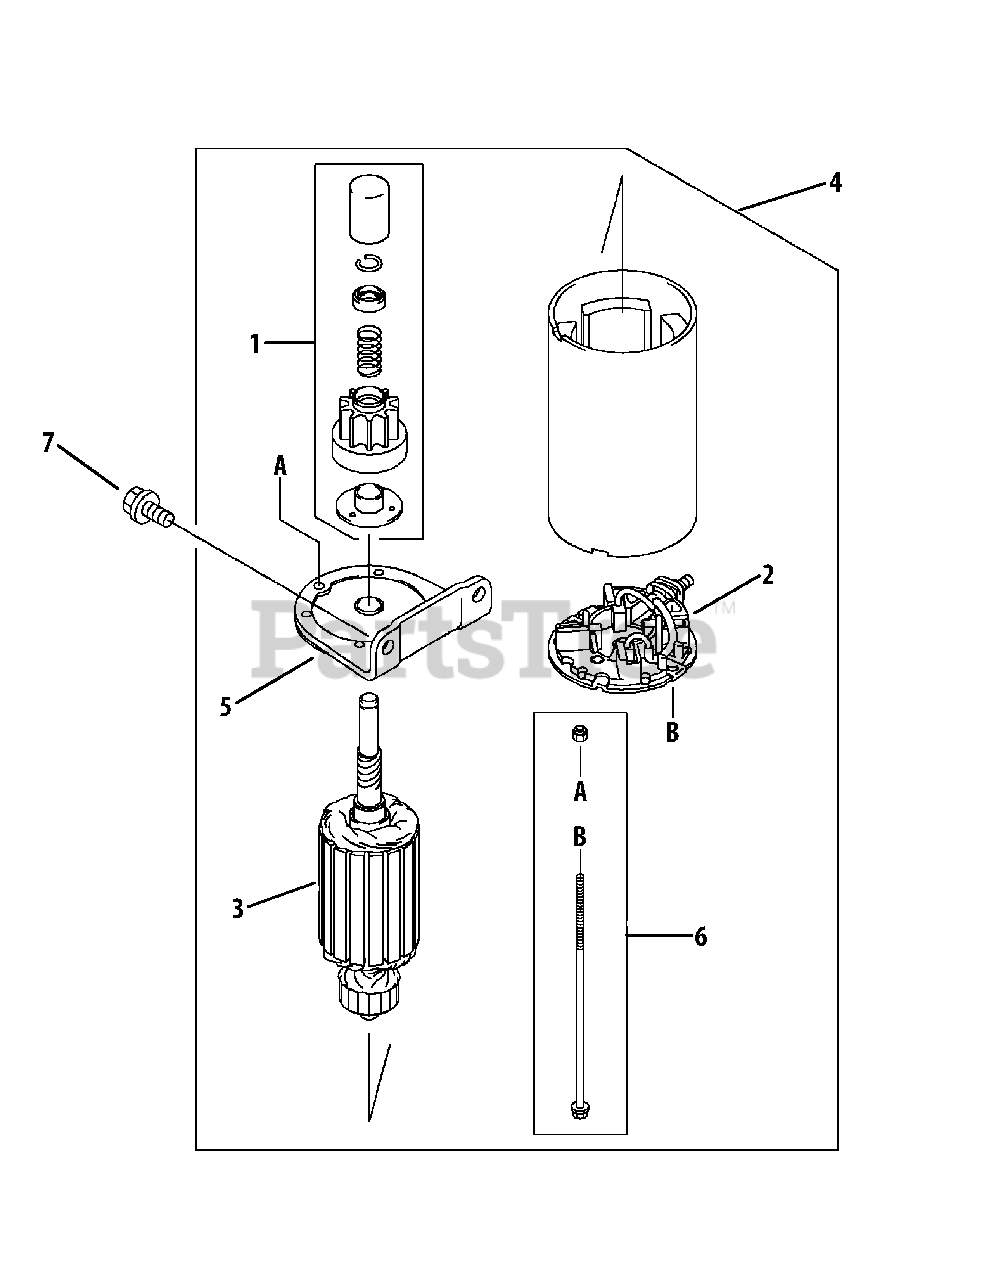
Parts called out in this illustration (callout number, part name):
1	Gear Assembly
2	Brush
4	Starter Assembly
5	Bracket
